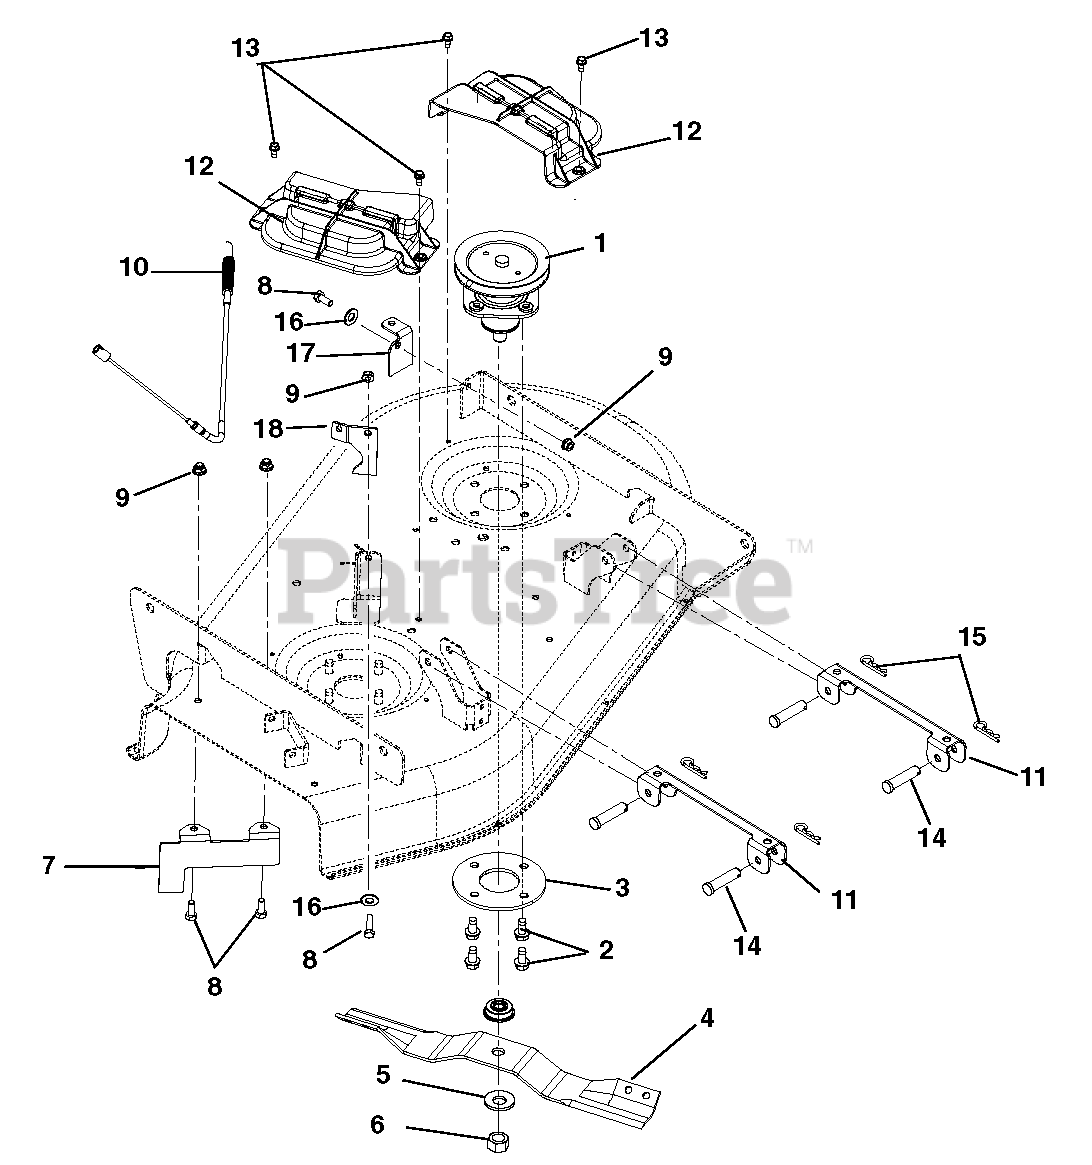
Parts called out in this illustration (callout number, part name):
1	Assembly, Spindle
2	Screw, Tapping .38-16 x .75 Hex Washer Head
3	Plate, Reinforcement Spindle
4	Blade, 17.2" x .156
5	Washer, Beveled .63 x 1.625 x .14
6	Nut, Hex .62-18
7	Bracket, Baffle Discharge 34"
8	Bolt, Hex .31-18 x .75 Grade 5
9	Nut, .31-18 Nyloc Flange
10	Cable, PTO
11	Bracket, Stabilizer Link
12	Cover, Belt Molded
13	Screw, Tapping .25-20 x .50 Hex Washer Head
14	Pin, Clevis .375 x 2.00
15	Pin , Bow Tie Locking Cotter
16	Washer, Flat-Steel .38 x .875 x .083
17	Bracket, Spring Anchor
18	Bracket, Cable Mount Adapter
